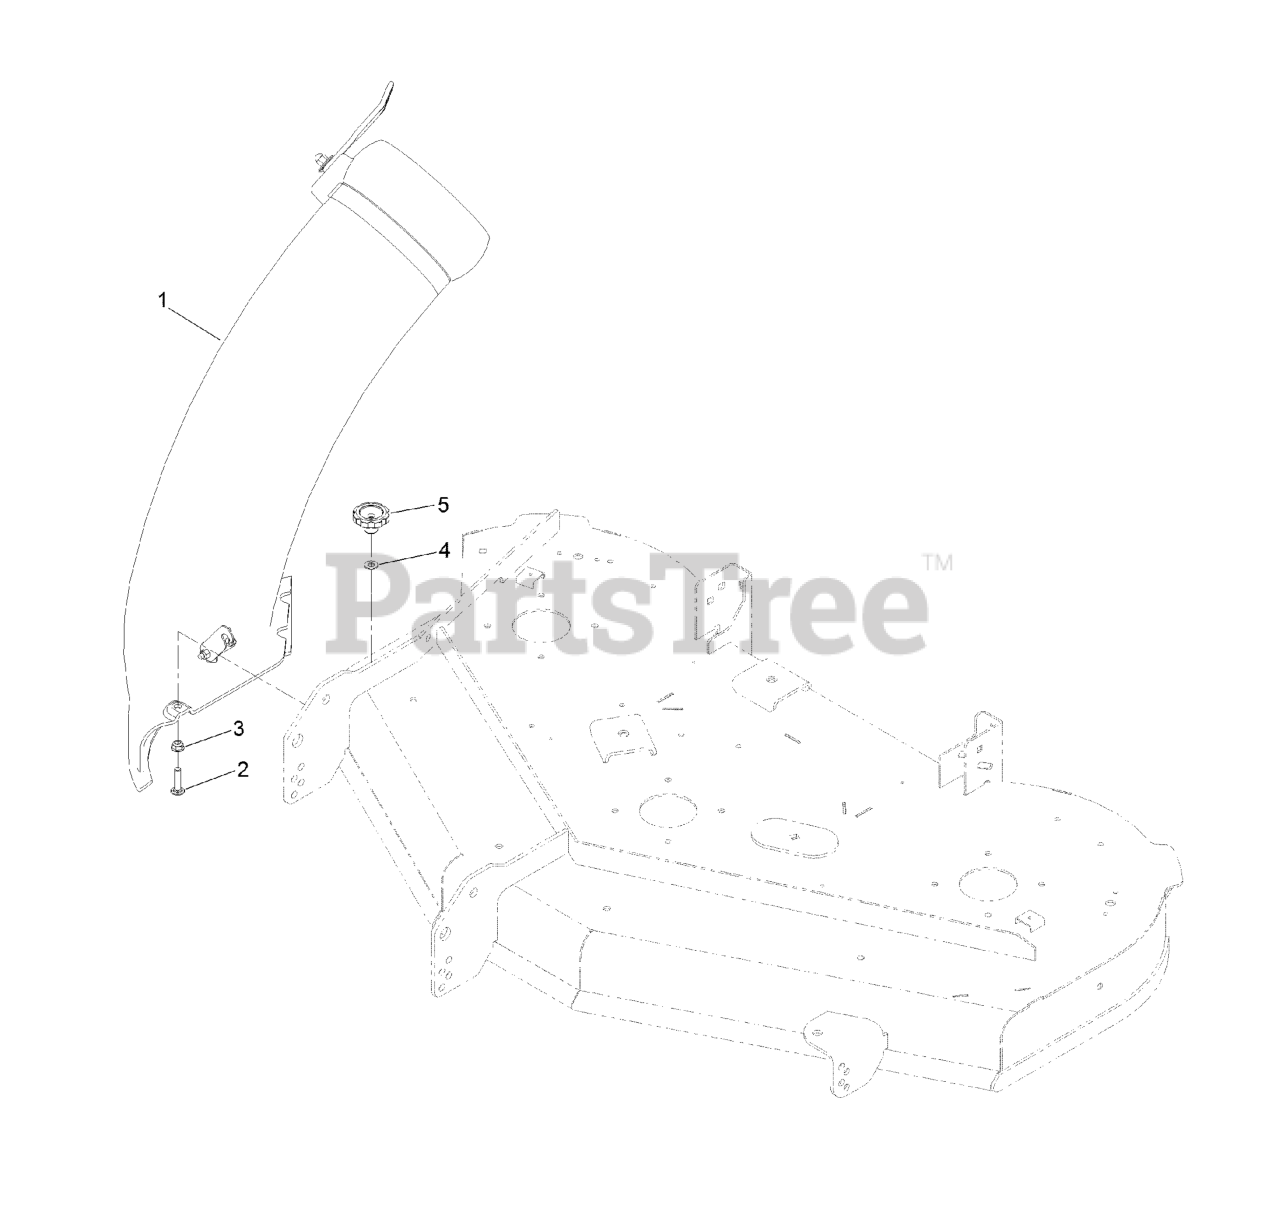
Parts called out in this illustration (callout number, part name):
1	50 INCH CHUTE ASM
2	BOLT-CARRIAGE 5/16-18 X 1 3/8 SHORT NECK
3	NUT-HF, NI
4	WASHER-PLAIN
